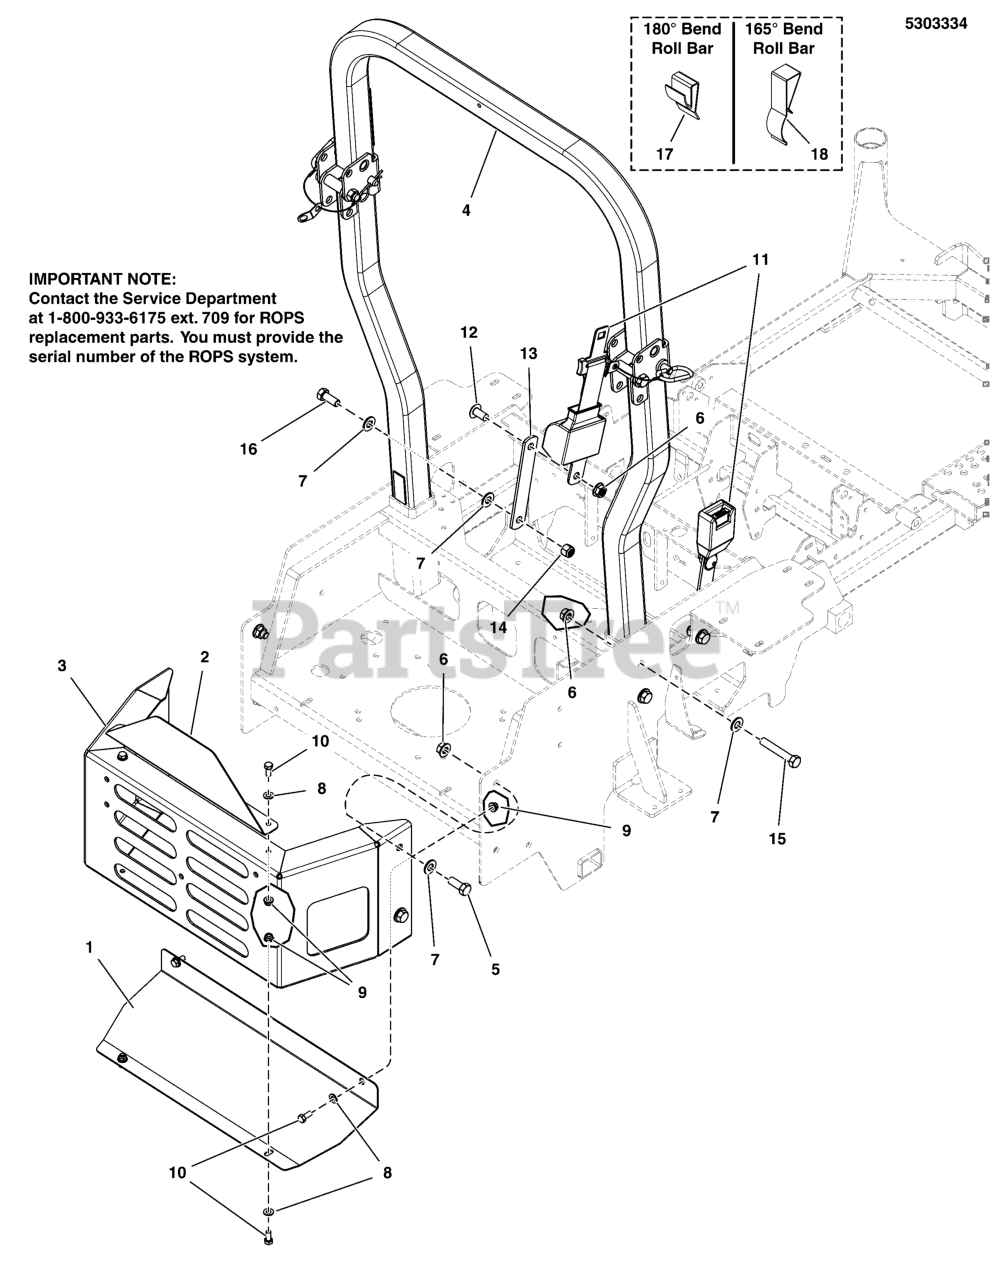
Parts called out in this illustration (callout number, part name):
1	PLATE, HEAT SHIELD, S125XT - BLACK
2	PLATE, CARB PROTECTOR - RED
3	WELD, BUMPER, S125XT - RED
4	ROPS (Call 1-800-933-6175 ext. 2193 if replacing a ROPS)
5	BOLT, 1/2-13 X 1-1/4 GD5 CZ
6	NUT, Hex Flange, Nylock, 1/2-13
7	WASHER, 1/2 SAE
8	WASHER, 5/16" SAE
9	NUT, 5/16-18 HEX NYLOCK FLANGE
10	BOLT, 5/16-18 X 3/4 GD5
11	SEAT BELT, RETRACTING - ASSM
12	SCREW, 1/2-13 X 1.00, SHCS
13	BAR, MOUNT, SEAT BELT, S125XT - BLK
14	NUT, 1/2-13 HEX NYLON LOCK
15	BOLT, 1/2-13 X 3" GD5 CZ
16	BOLT, 1/2-13 X 1-1/2 GD5 CZ
17	ANTI-RATTLE SPRING, FEMCO #230328972 (SV)
18	ANTI-RATTLE SPRING, ROPS, 165 DEGREE (SV)
